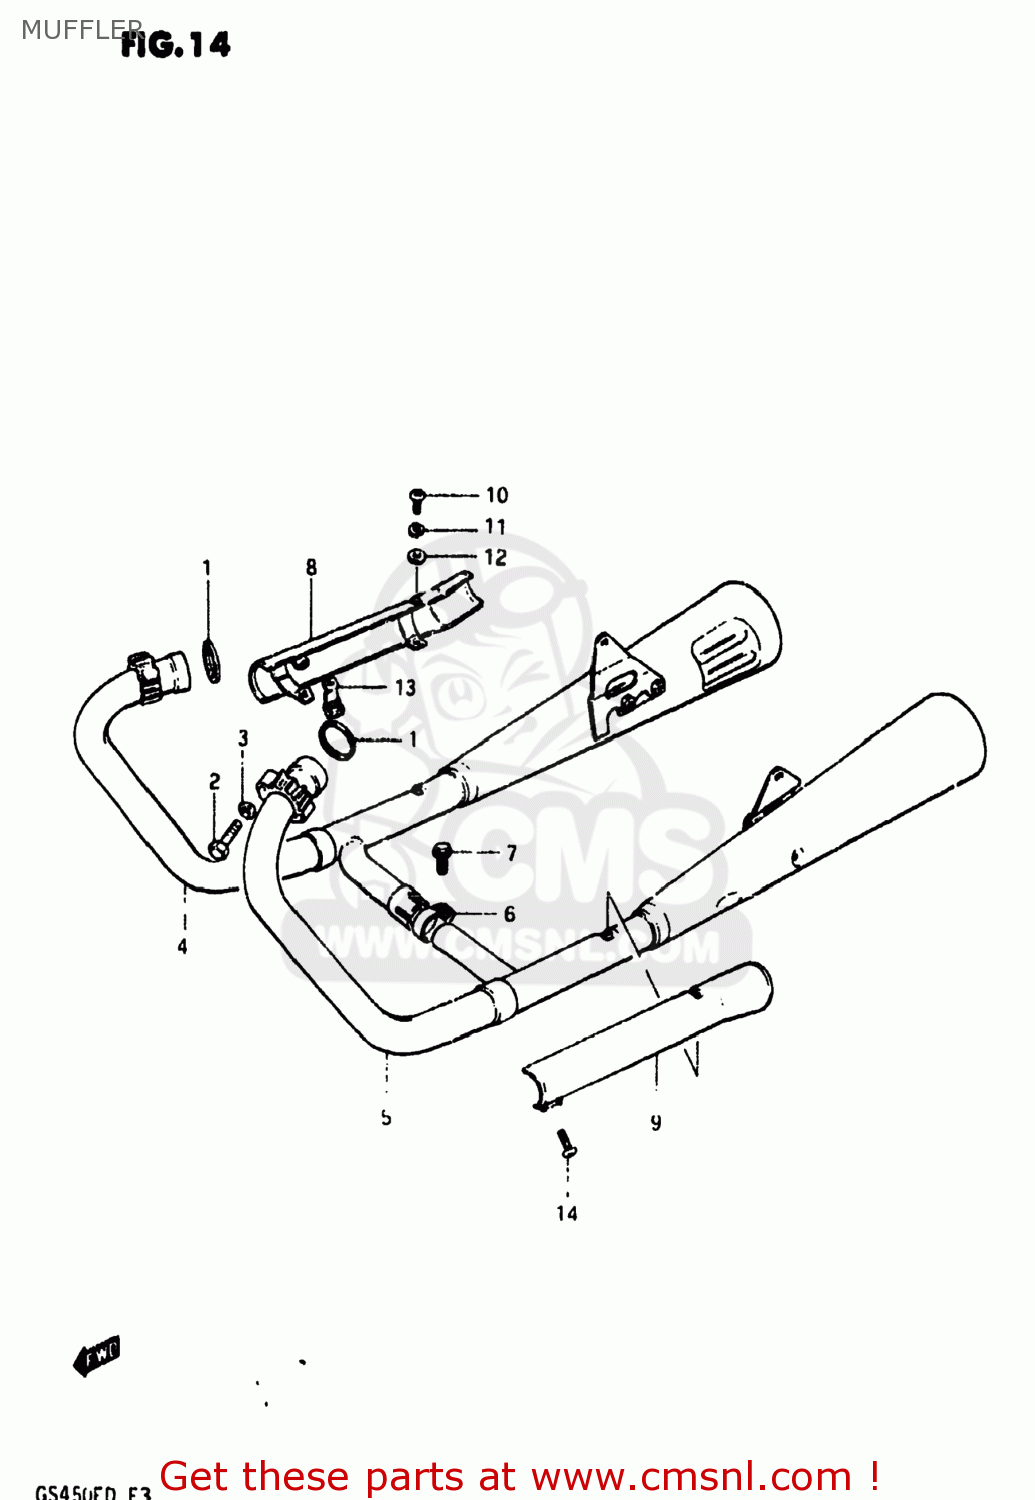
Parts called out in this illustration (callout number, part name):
1	GASKET,EXHAUST PIPE (NAS)
2	BOLT 8X40
3	LOCK WASHER
4	MUFFLER ASSEMBLY
5	MUFFLER ASSEMBLY
6	CLAMP
7	BOLT
8	COVER,MUFFLER
9	COVER,MUFFLER
10	SCREW
11	LOCK WASHER
12	WASHER
13	CLAMP,MUFFLER COVER
14	SCREW
